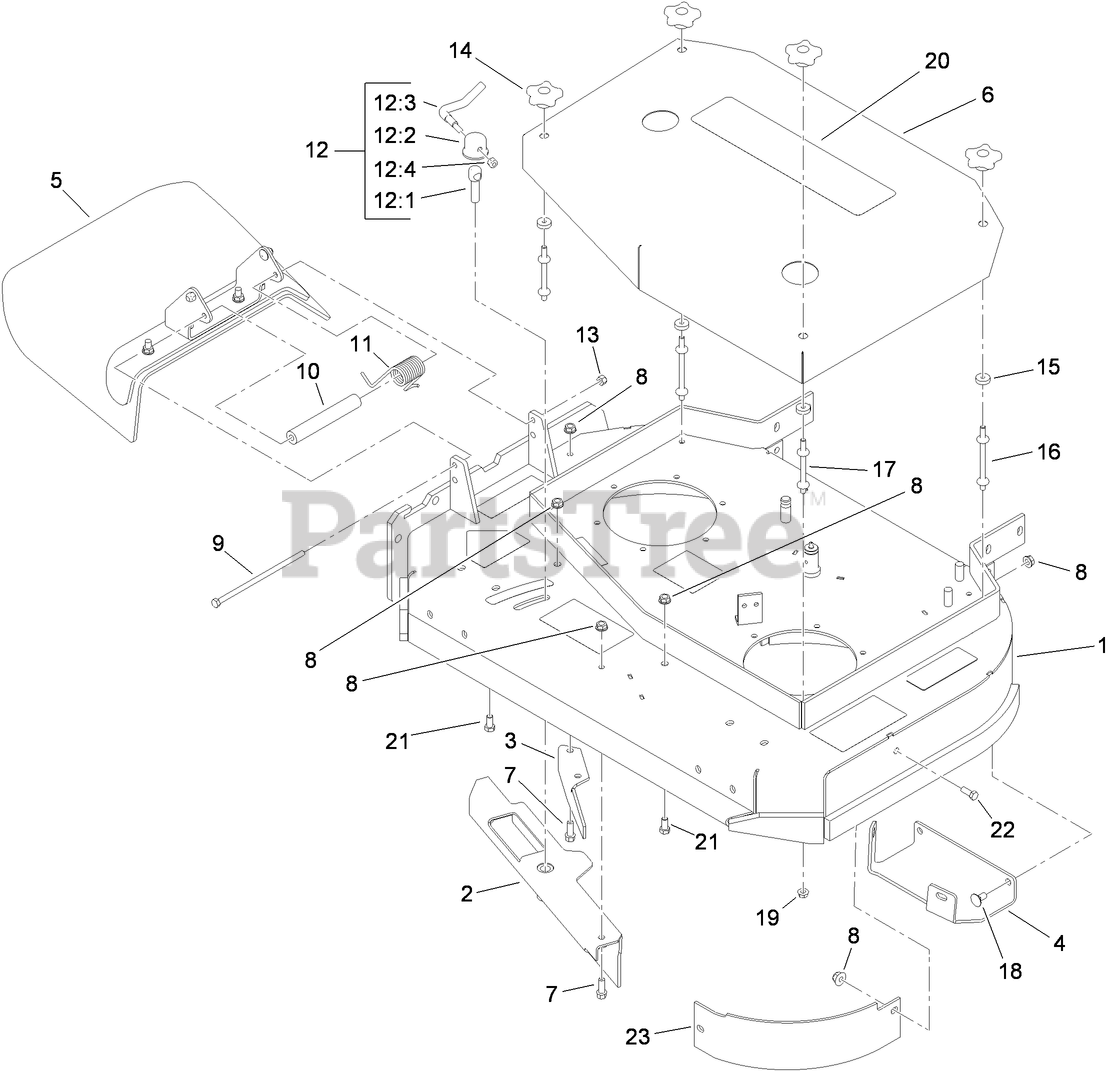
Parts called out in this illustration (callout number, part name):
1	DECK ASM
2	BAFFLE-ADJUSTABLE
3	BAFFLE-DISCHARGE
4	PLATE-SKID
5	DEFLECTOR ASM
6	COVER-DECK
7	SCREW-HWH
8	NUT-HF, NI
9	SCREW-HH
10	SPACER
11	SPRING-TORSION
12	LEVER ASM
12:1	Screw-Lock
12:2	CAP-LOCK
12:3	Lever-Lock
12:4	NUT-LOCK, NI
13	NUT-LOCK, NI
14	KNOB-HANDLE
15	WASHER
16	STUD-SHIELD, BELT (LONG)
17	STUD-SHIELD, BELT (SHORT)
18	BOLT-CARR
19	NUT-HF
21	SCREW-HH
22	SCREW-HH
23	BAFFLE-FRONT, LH
